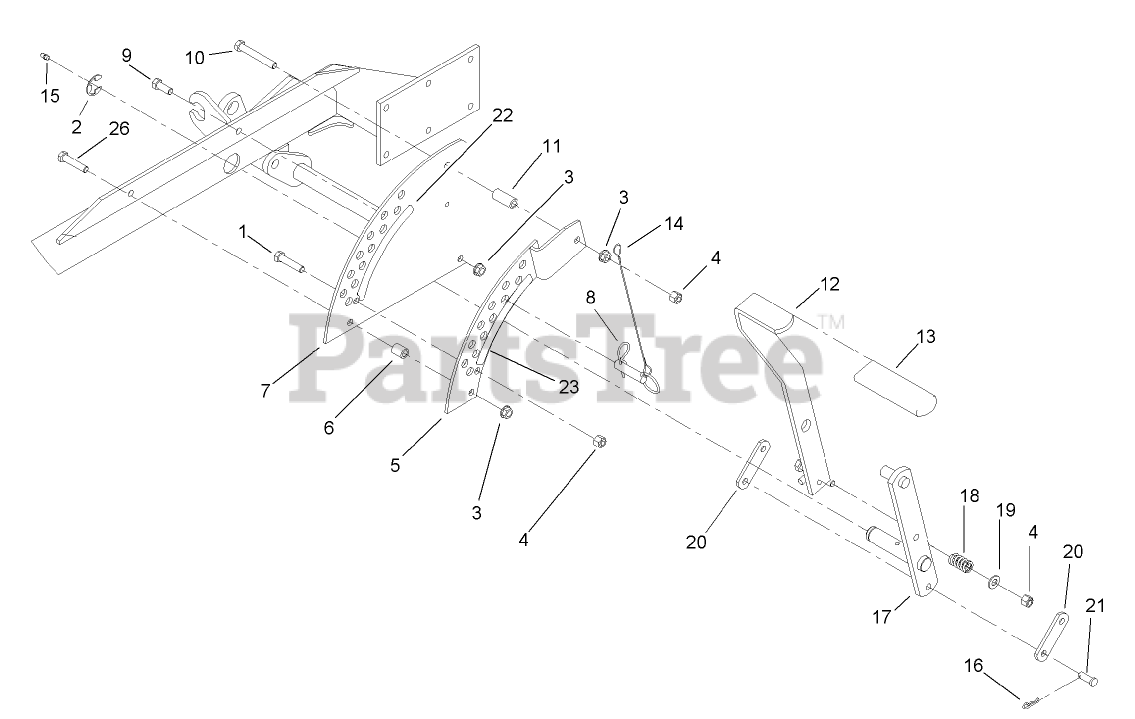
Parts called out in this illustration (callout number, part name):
1	SCREW-HH
2	RING-RETAINING, EXT
3	NUT-HHF, WHIZ
4	NUT-LOCK, NI
5	PLATE-LIFT, DECK
6	BUSHING-LEVER, LIFT
7	PLATE-LIFT, DECK
8	PIN-COTTER
9	SCREW-HH
10	SCREW-HH
11	BUSHING-LEVER, LIFT
12	HANDLE-LIFT
13	GRIP-LEVER, LIFT
14	PIN-HITCH (W/LANYARD)
15	FITTING-GREASE
16	PIN-COTTER
17	ARM-LIFT
18	SPRING-COMPRESSION
19	WASHER-FLAT
20	ARM-LIFT, DECK
21	PIN-CLEVIS
22	DECAL-DECK HEIGHT, OUTER
23	DECAL-DECK HEIGHT, INNER
26	SCREW-HH
